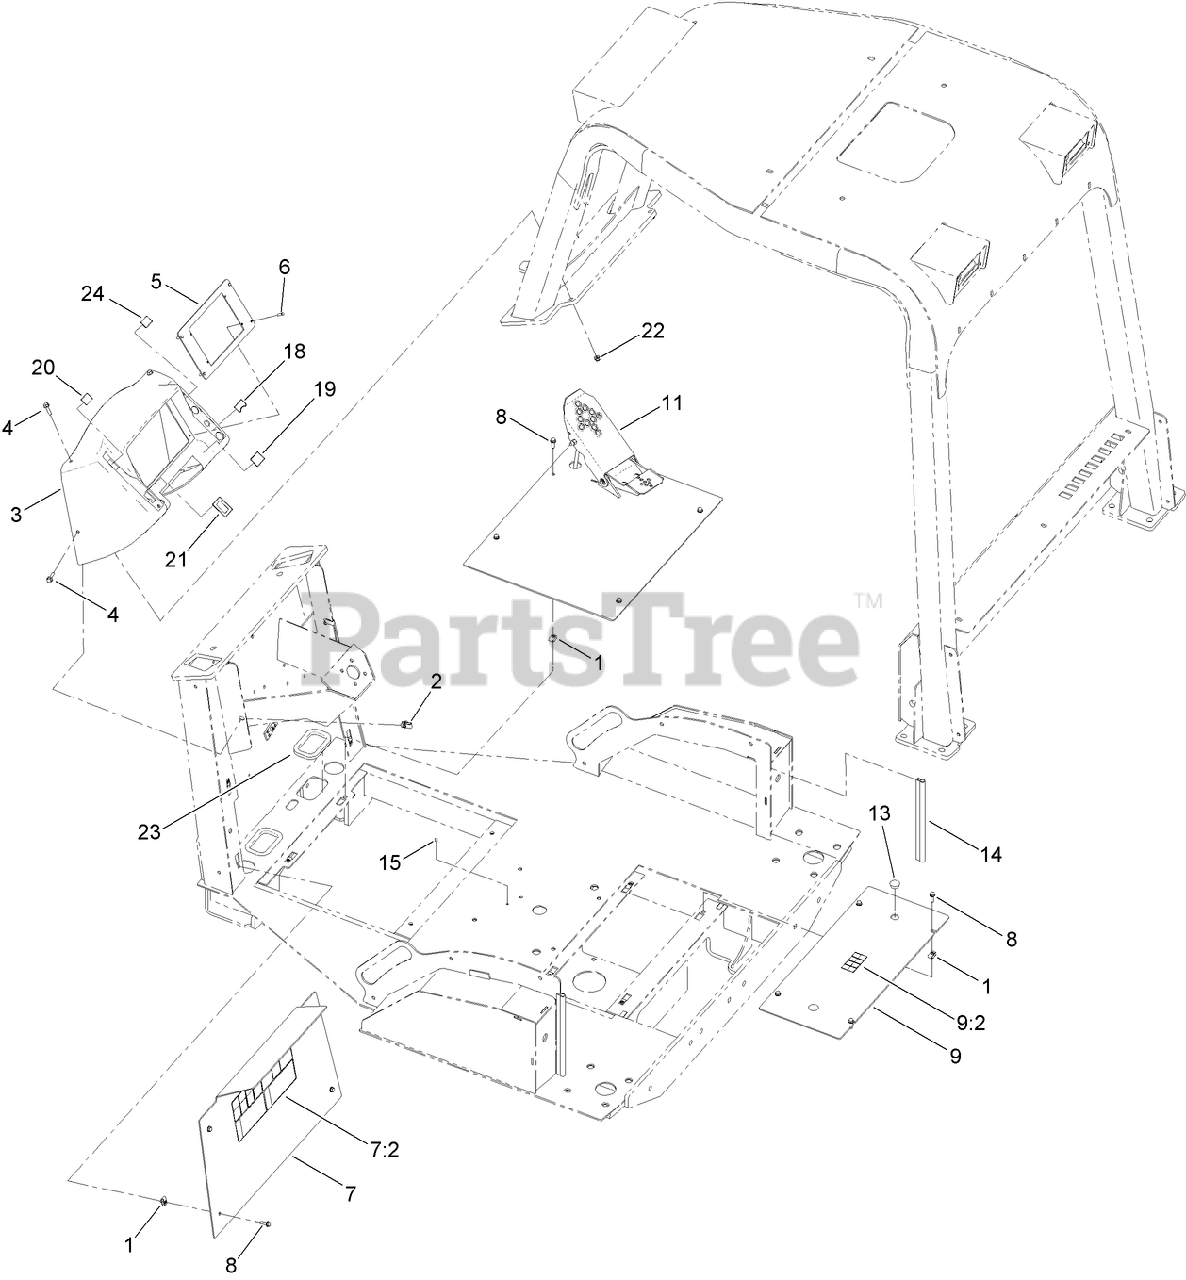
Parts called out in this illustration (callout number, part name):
1	NUT-CLIP, U
3	DASH-PANEL
4	SCREW-HHF
5	PLATE-MOUNT, DISPLAY
6	SCREW-HH
7	KICK PANEL ASM
7:2	DECAL-SAFETY
8	SCREW-HHF
9	BATTERY COVER ASM
9:2	DECAL-WARNING, BATTERY
11	PEDAL ASM
13	PLUG-DOME
14	SEAL-Hood
15	PLUG-DOME
18	DECAL-AUX POWER
19	DECAL-IGNITION
20	DECAL-LOCK, DIFFERENTIAL
21	DECAL-AUX POWER
22	NUT-LOCK, HHF
23	TRIM-BATTERY
24	DECAL-BRAKE, PARKING
